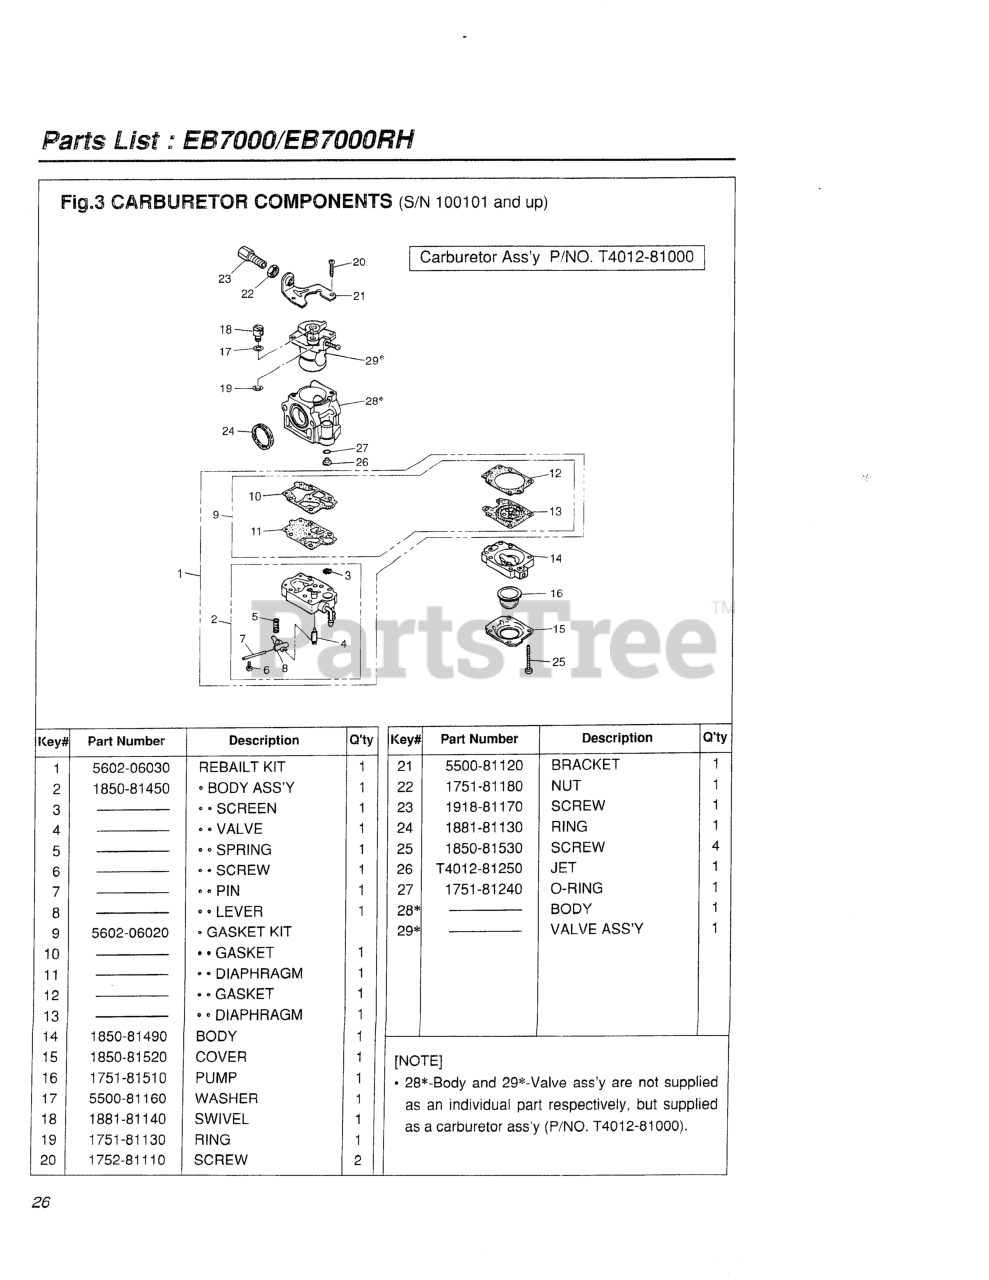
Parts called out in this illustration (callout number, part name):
2	BODY, PUMP
3	SCREEN
4	VALVE, INLET
6	SCREW
7	PIN
8	LEVER
10	GASKET
11	DIAPHRAGM
12	GASKET
13	DIAPHRAGM
14	BODY, PURGE
15	COVER, PUMP
16	PUMP, PRIMING
17	WASHER
18	SWIVEL
19	RING
20	SCREW
22	NUT, CABLE ADJUSTER
23	SCREW, CABLE ADJUSTER
24	RING, PACKING
25	SCREW
26	JET
27	RING, O
28	CARBURETOR (WYK-123-1)
29	CARBURETOR (WYK-123-1)
